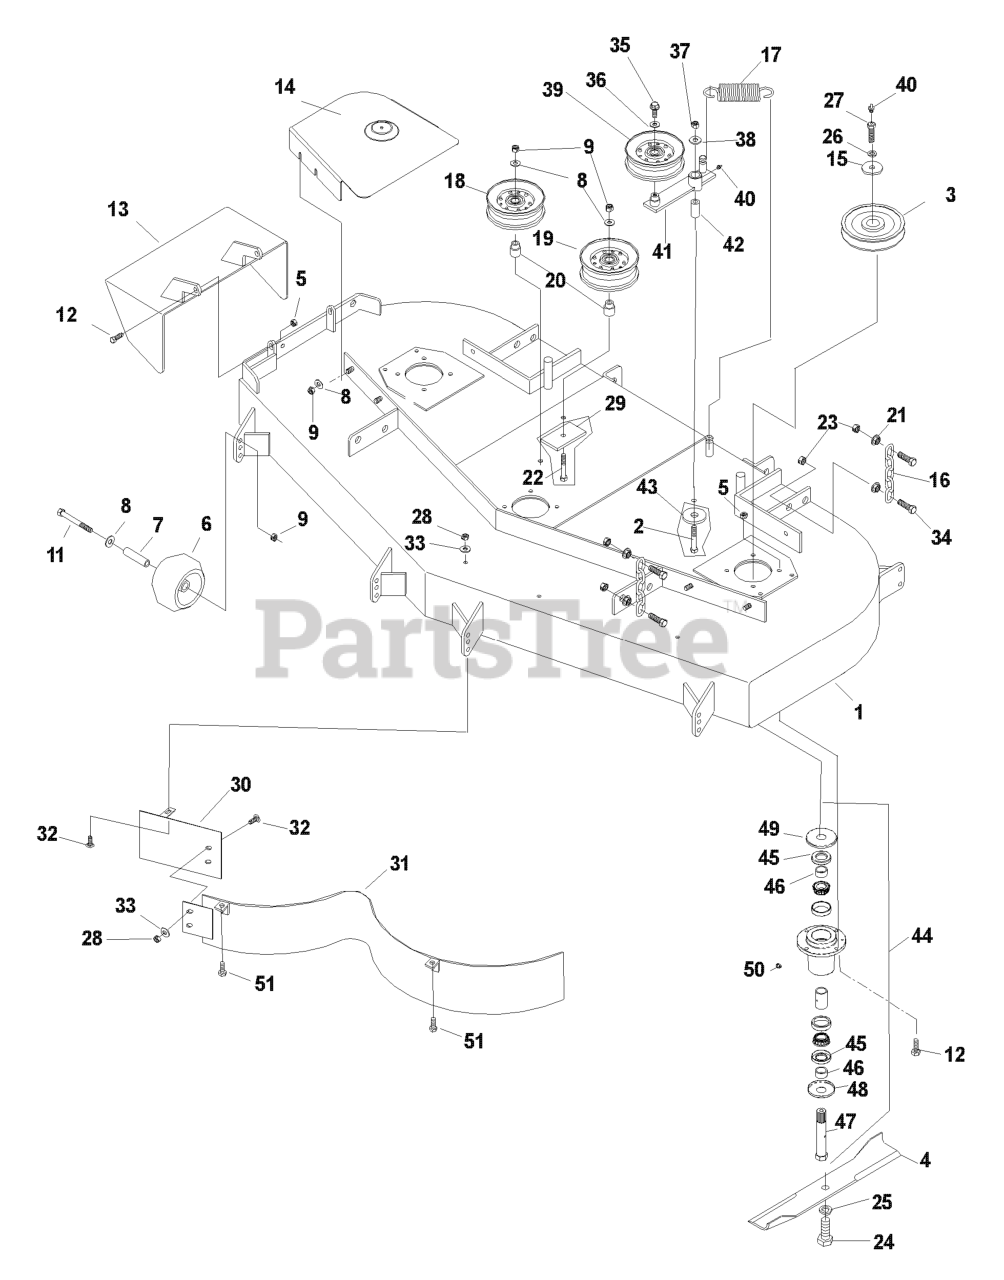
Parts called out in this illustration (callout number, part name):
1	DECK W/DECALS 52" HUS WSL
2	HCS 1/2C X 3 1/4
3	PULLEY - 52"
4	BLADE OEM 18"
5	NUT 5/16 NYLOC
6	ANTI-SCALP ROLLER
8	WASHER 3/8 FLAT
9	NUT 3/8-16 NYLOC
11	HCS 3/8C X 3 1/2
12	HCS 5/16C X 1 1/4
13	DISCHARGE CHUTE ORANGE
14	RT 52 SHIELD, ORANGE
15	SPINDLE WASHER
16	LIFT CHAIN
17	DECK SPRING
18	IDLER PULLEY
19	IDLER PULLEY (TALL)
20	IDLER BUSHING
21	NUT 7/16C WHIZ
22	SCREW 3/8C X 2 3/4 HEX CAP
23	NUT 7/16C CENTERLOCK
24	HCS 5/8F X 1 1/4
25	LOCKWASHER 5/8
26	WASHER 7/16 LOCK
27	DRILLED BOLT 7/16-20 X 1 1/2"
28	NUT 5/16C CENTERLOCK
29	SUPPORT PLATE
30	CENTER BAFFLE - 52"
31	MAIN BAFFLE 52"
32	CARRIAGE BOLT 5/16C X 5/8"
33	WASHER 5/16 FLAT
34	HCS 7/16C X 1 1/2
35	4CS 3/8C X 1 SERRATED HEAD
36	WASHER 3/8 FLAT
37	NUT 1/2-13 HEX NYLOC ZD
38	WASHER 1/2 FLAT
39	IDLER PULLEY
40	ZERK
42	PIVOT BUSHING
43	WASHER, SUPPORT
44	SPINDLE ASSY - 52/61"
45	SHAFT SEAL
47	52/61 SPINDLE - SPLINED SHAFT
48	BOTTOM DUST CAP
49	TOP DUST CAP
50	PLUG-VENTED
51	HCS 5/16C X 3/4
